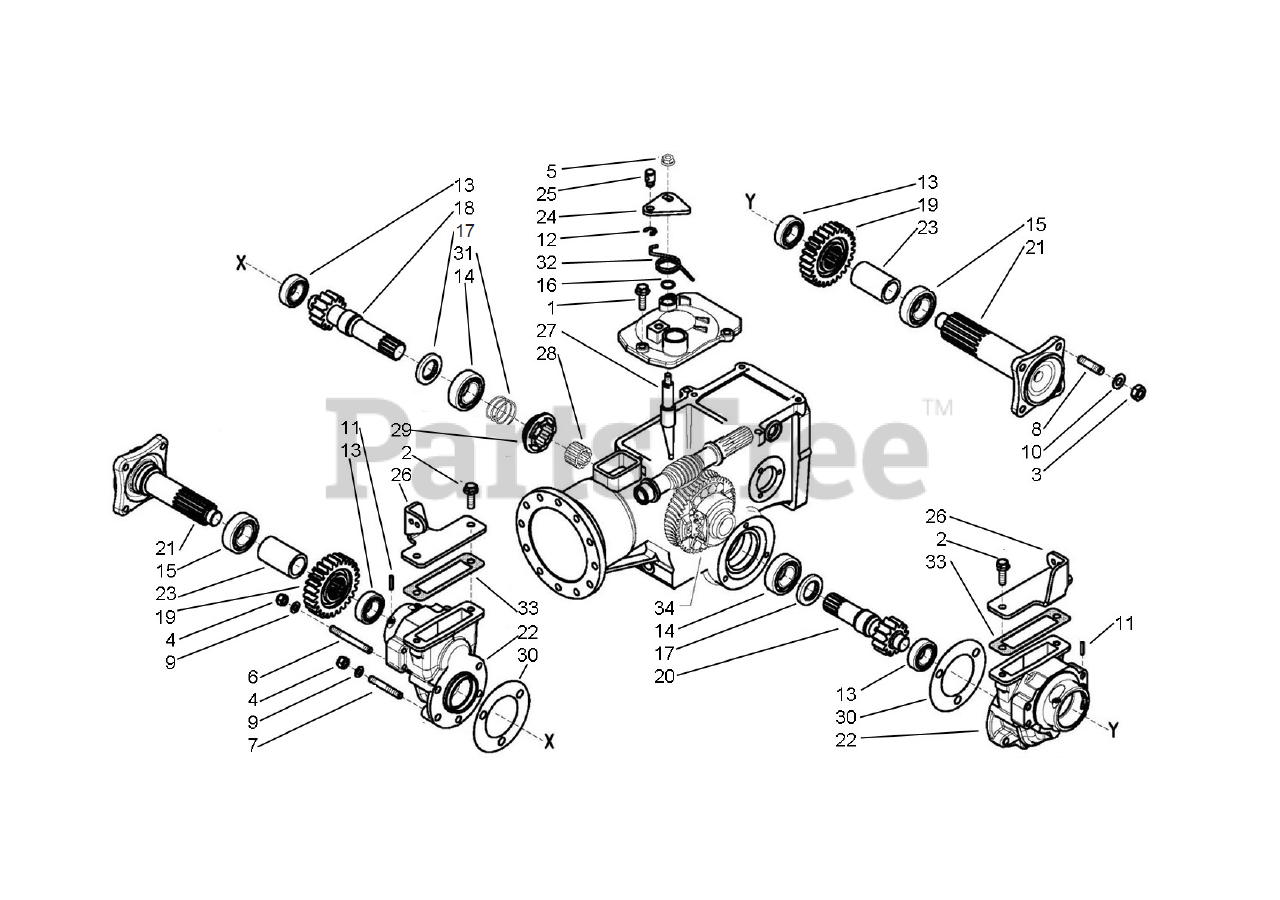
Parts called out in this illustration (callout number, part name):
1	SCREW TE M8X25
2	SCREW TE M8X25
3	NUT, M10
4	NUT, LOCK M8
5	NUT, LOCK M8
6	STUD M8X80X28X16
7	STUD M8X52X14X18
8	STUD BOLT M10X40X24X12
9	SPRING WASHER 8 4 DIN 137
10	SPRING WASHER 10 5 DIN137
11	ROLL PIN
12	SEEGER RING E 6 UNI 7434
13	BEARING
14	BEARING
15	BEARING
16	O-RING 2056 (14 00X1 78)
17	OIL SEAL
18	RH REDUCTION SHAFT D25
19	GEAR
20	SHORT LH REDUCTION SHAFT D23
21	AXLE SHAFT
22	REDUCTION BOX
23	SPACER
24	LEVER
26	STOP
28	SPACER
29	COUPLING
30	GASKET
31	SPRING
32	SPRING
33	COVER GASKET
34	DIFFERENTIAL GEAR
